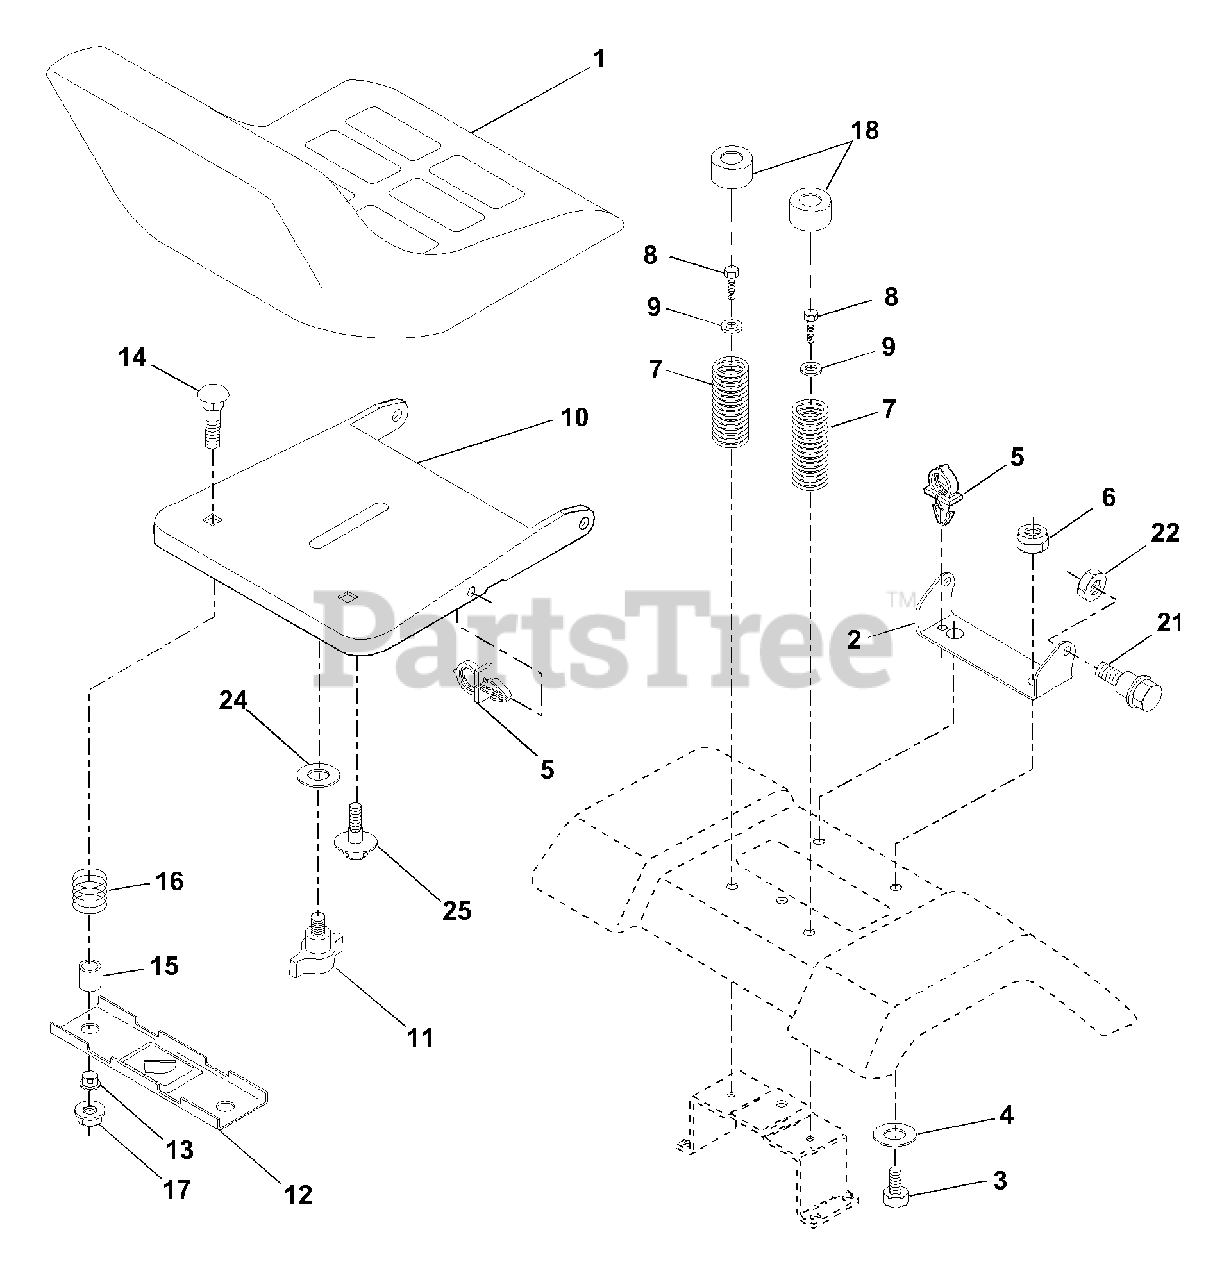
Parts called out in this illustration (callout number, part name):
1	Seat
2	Bracket Pivot Seat 8 720
3	Bolt Fin Hex 3/8-16unc X 1
4	Washer 13/32 X 1 X 10 Ga
5	Clip Push-In
6	Nut Hex w/Ins. 3/8-16 Unc
7	Spring Seat Cprsn 2 250 Blk Zi
8	Screw 3/8-16 X 1-1/2
9	Washer 13/32 X 1 X 14 Ga.
10	Pan Seat
11	Knob Seat 1/2-13 UNC Blk
12	Bracket Mounting Switch
13	Bushing Snap Blk Nyl 50 Id
14	Bolt Rdhd Sqnk 1/4-20x1-1/2
15	Spacer Split 28x 96 Yel Zinc
16	Spring Cprsn 1 27 Blk Pnt
17	Nut Lock 1/4 Lge Flg Gr 5 Zinc
18	Cap Spring Seat
21	Bolt Shoulder 5/16-18 Unc
22	Nut Hex Lock W/Ins 5/16-18
24	Washer 17/32 X 1 X 12 Ga.
25	Bolt Shoulder 5/16-18 X 62
